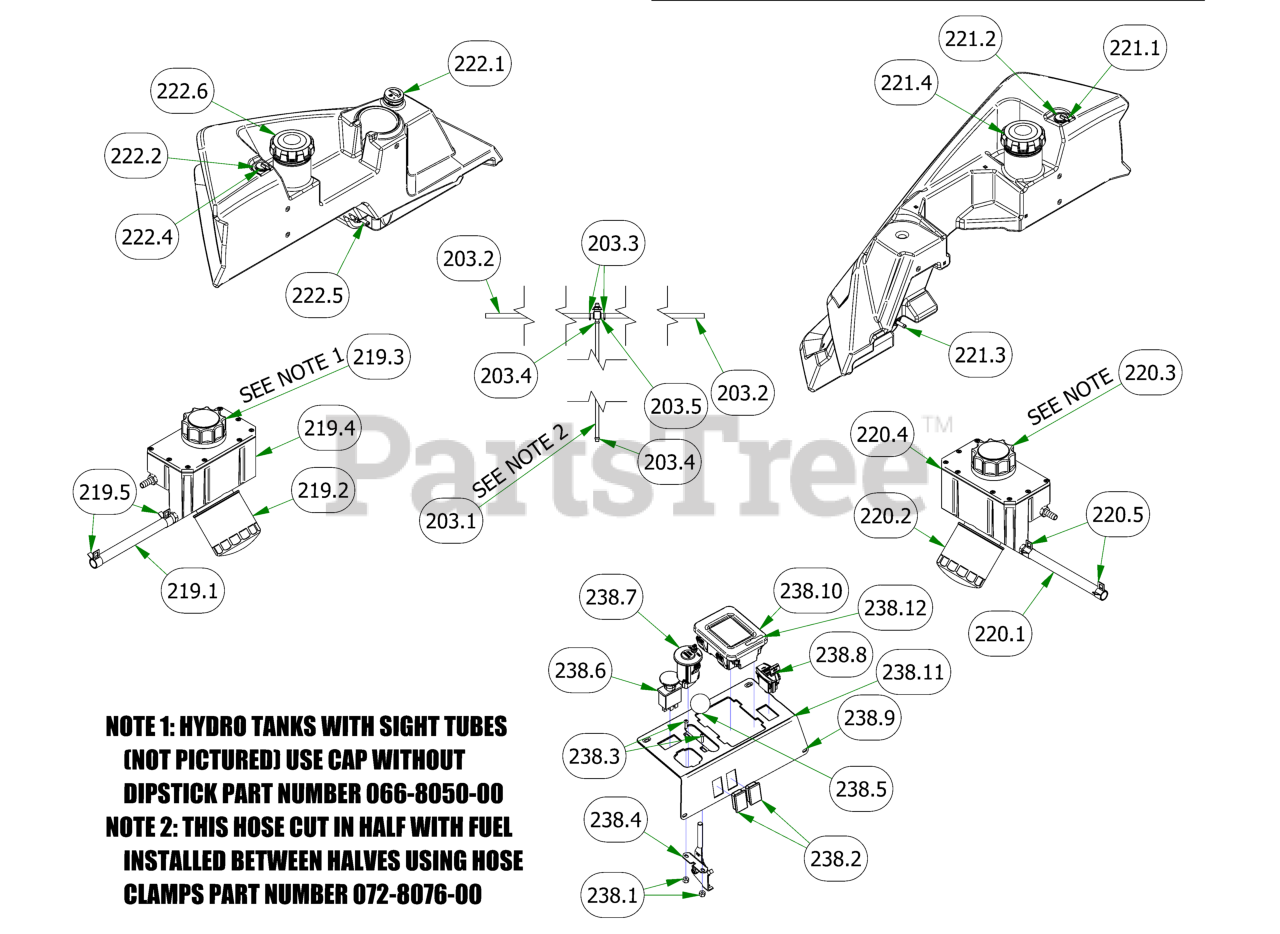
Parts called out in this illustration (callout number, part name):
203	2023 Rebel Rogue Renegade Fuel Line for Kohler
203.1	1/4" Fuel Line Hose
203.2	5/16" fuel line hose
203.3	5/16 Fuel Line Clamp
203.4	1/4 Fuel Hose Clamp
203.5	3 Way Fuel Shut-Off Valve 5/16 x 5/16 x 1/4
219	LH Rogue Hydro Tank Assy
219.1	1/2 Clear Braded Hose Priced/Foot
219.2	Hydraulic Filter
219.3	Hydraulic Tank Cap W/Dipstick
219.4	2019 Left Outlaw Gen2 Hydro Tank Suspension Only
219.5	1/2 Hose Clamp
220	RH Rogue Hydro Tank Assy
220.1	1/2 Clear Braded Hose Priced/Foot
220.2	Hydraulic Filter
220.3	Hydraulic Tank Cap W/Dipstick
220.4	2019 Right Outlaw Gen2 Hydro Tank Suspension Only
220.5	1/2 Hose Clamp
221	2019 Right Rebel, Rogue, Renagade Fuel Tank (GAS)
221.1	Roll Over Valve Grommet
221.2	Rollover Valve
221.3	Fuel Pick-up
222	2019 Left Rebel, Rogue, Renegade Fuel Tank (GAS)
222.1	Fuel Gauge with Grommet
222.2	Roll Over Valve Grommet
222.3	Fuel Gauge Grommet
222.4	Rollover Valve
222.5	Fuel Pick-up
238	Renegade Control Panel Assembly
238.1	10-24 Nylon Insert Locknut
238.2	Light Plug
238.3	10-24 X 5/8 BS Button Head Bolt
238.4	Universal Throttle Head - 2012
238.5	Throttle Knob
238.6	PTO Switch
238.7	2019 Push to Start Switch w/fob
238.9	2019 Outlaw Digital Control Panel
238.10	2019 LED Display
238.11	2022 Renegade (Gas) Control Panel Decal
238.12	2022 Digital Display Decal
